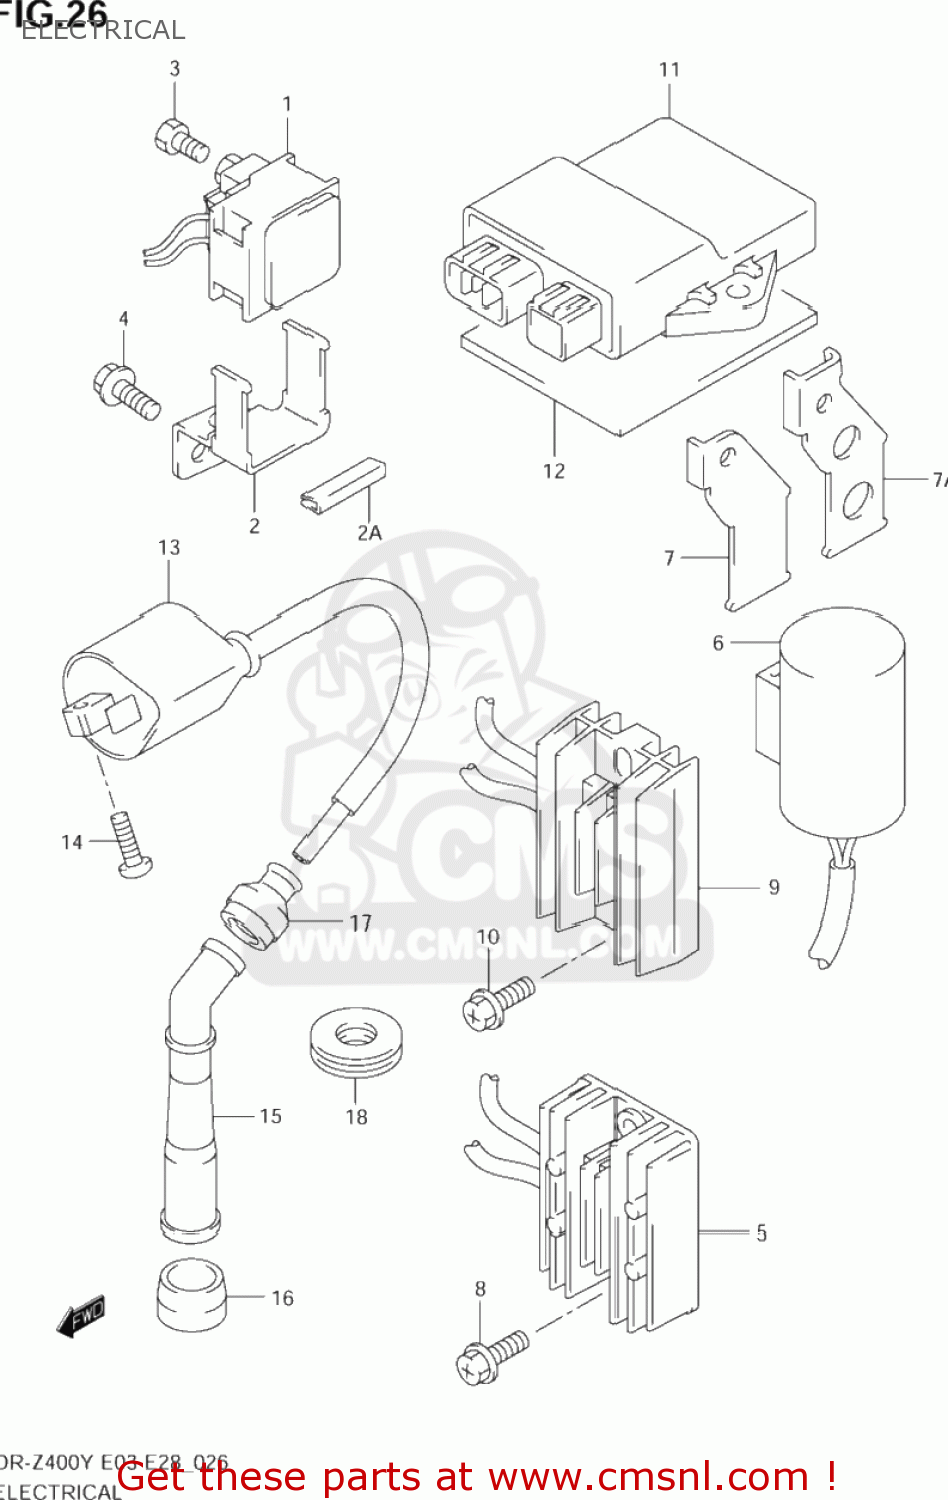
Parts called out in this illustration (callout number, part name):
1	RELAY ASSY,STARTING MOTOR
2	BRACKET,STARTING MOTOR RELAY
2A	PROTECTOR,STARTING MOTOR LEAD
3	SCREW(6X8)
4	BOLT
5	RECTIFIER ASSY
6	CONDENSER ASSY
7	BRACKET,CONDENSER
7A	BRACKET,CONDENSER
8	BOLT
9	RECTIFIER ASSY
10	BOLT
11	CDI UNIT
12	PROTECTOR(170X95X3.0)
13	COIL ASSY,IGNITION
14	BOLT
15	CAP,SPARK PLUG
16	SEAL,SPARK PLUG CAP
17	SEAL,HIGH TENSION CORD
18	COVER,SPARK PLUG CAP
